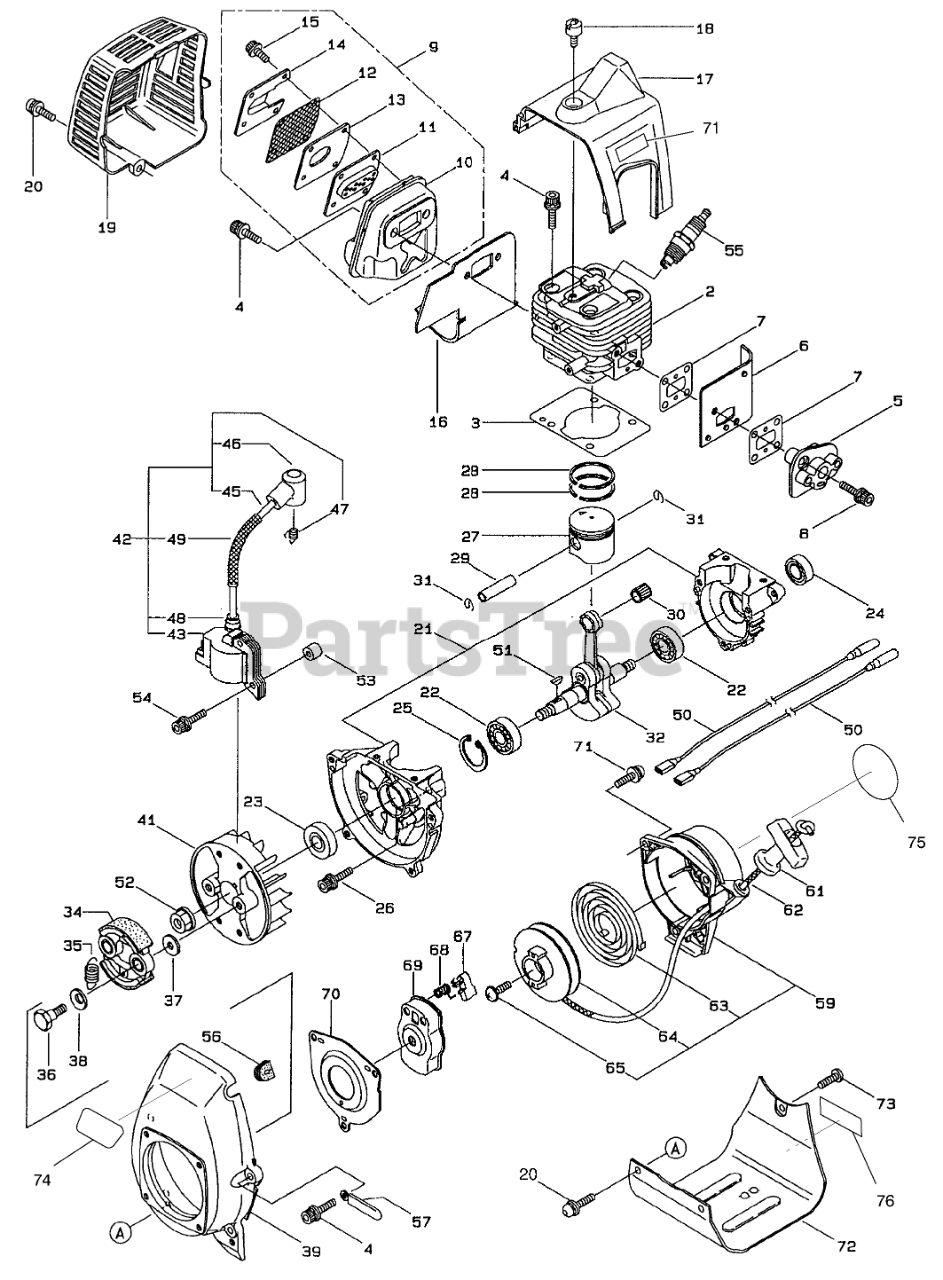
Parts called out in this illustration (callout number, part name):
2	CYLINDER
3	GASKET
5	INSULATOR
6	DUCT - AIR
7	GASKET
8	SCREW
9	Muffler Assembly (Incl. Ref. #10-15)
10	MUFFLER
11	PLATE
12	SCREEN
13	GASKET
14	OUTLET - EXHAUST
15	CAPSCREW
16	GASKET
17	COVER - CYLINDER
18	COVER - KNOB,TOP
19	COVER - MUFFLER
20	CAPSCREW
21	CRANKCASE
22	BEARING
23	SEAL - OIL
24	SEAL - OIL
25	RING - SNAP
27	PISTON
28	RING - PISTON
29	PIN - PISTON
30	BEARING - NEEDLE
31	CIRCLIP
32	CRANKSHAFT
34	SHOE - CLUTCH
35	SPRING - CLUTCH
36	BOLT - CLUTCH
37	WASHER
38	WASHER - WAVE
39	COVER - FAN
41	ROTOR
42	Ignition Coil Assembly (Incl. Ref. #43-49)
45	CABLE - IGNITION
46	CAP - PLUG
47	CONNECTOR
51	KEY - WOODRUFF
52	WASHER & NUT
53	SPACER
55	SPARK PLUG
56	GROMMET
57	CLAMP
59	Recoil Assembly (Incl. Ref. #60-65)
61	GRIP - STARTER
62	ROPE - STARTER
63	SPRING - SPIRAL
65	SCREW
68	SPRING - RETURN
69	STARTER
70	PLATE
71	DECAL - WARNING
72	STAND - ENGINE
73	SCREW
74	DECAL - TORO
75	DECAL - TORO
76	REPLACEMNT SERIAL PLT
